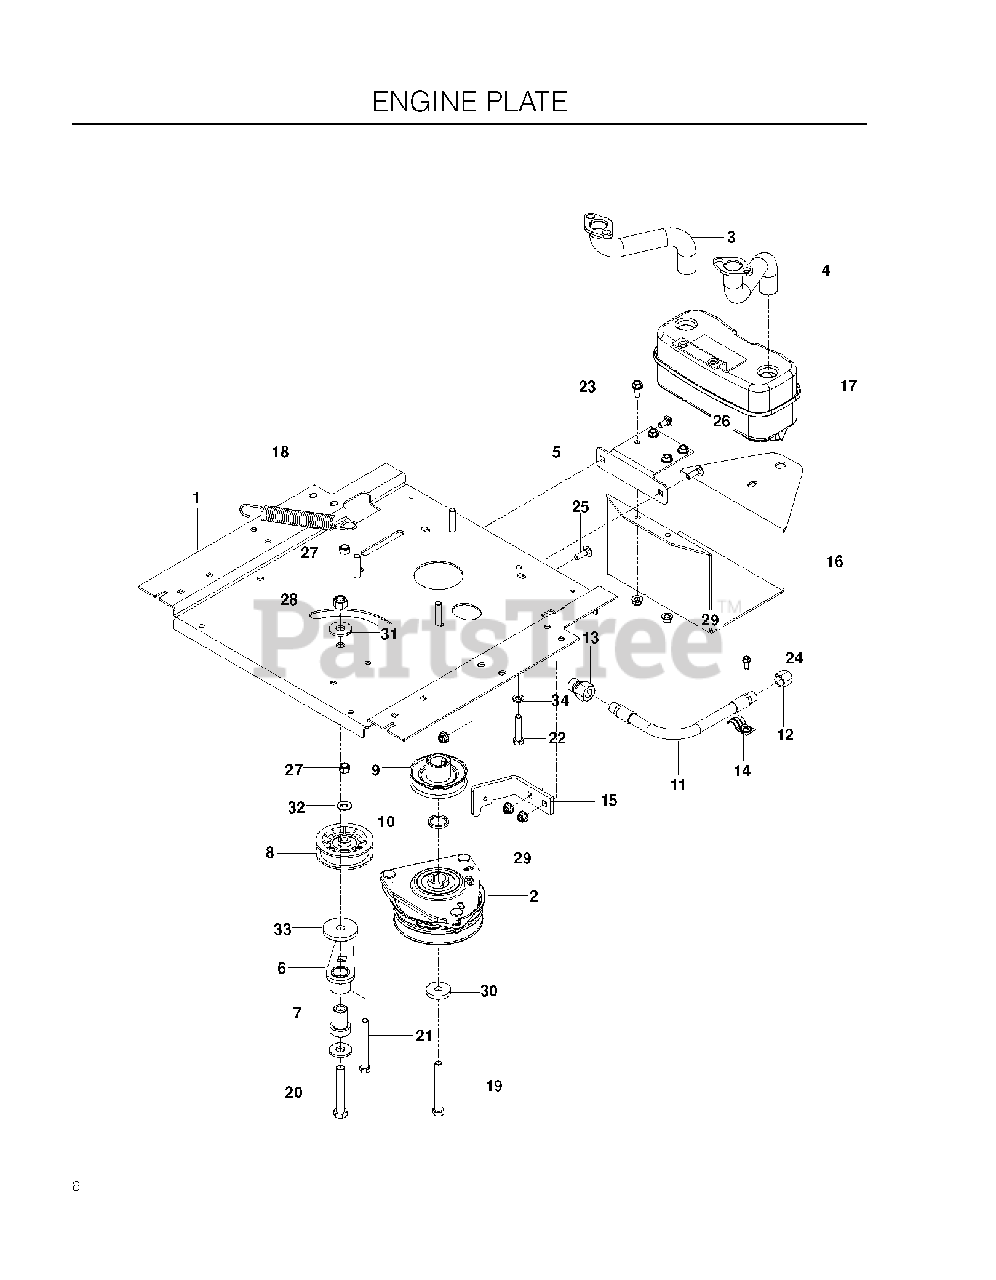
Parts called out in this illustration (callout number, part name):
1	PLATE, ENGINE BLK
2	CLUTCH.ELECTRIC.LT.48"*
3	TUBE.EXHAUST.LH.FR961/FR730
4	TUBE.EXHAUST.RH.FR961/FR730
5	BRACKET, MUFFLER, BLACK
6	IDLER ARM WELDMENT
7	IDLER SPINDLE
8	PULLEY, IDLER RAKE & ZTR
9	RP PULLEY, ENGINE
10	HUB PULLEY SPACER
11	OIL DRAIN HOSE
13	ADAPTER, OIL DRAIN
15	CLUTCH STOP OGR BLK
16	GUARD, MUFFLER, BLACK
17	MUFFLER ASM TWIN
18	SPRING, DECK DRIVE
19	HCS 7/16-20 X 2.5 GR8
20	HCS 1/2C X 3 1/4
21	HCS 3/8-16X3 1/2 GR5
22	BOLT, HCS 3/8-16X1-3/4
23	BOLT 5/16-18 X 3/4
24	SCREW 1/4 X 5/8
25	RHSNB 5/16C X 1
26	BOLT 5/16C X 3/4" CARRIAGE
27	NUT 3/8-16 NYLOC
28	RP NUT 1/2-13 HEX NYLOC ZD
29	5/16-18 NYLOC FLANGE NUT
30	CLUTCH, WASHER
31	WASH USS FLAT 1/2
32	WASHER 5/16 FLAT
33	HEAVY WASHER
34	SLW 3/8 STD
